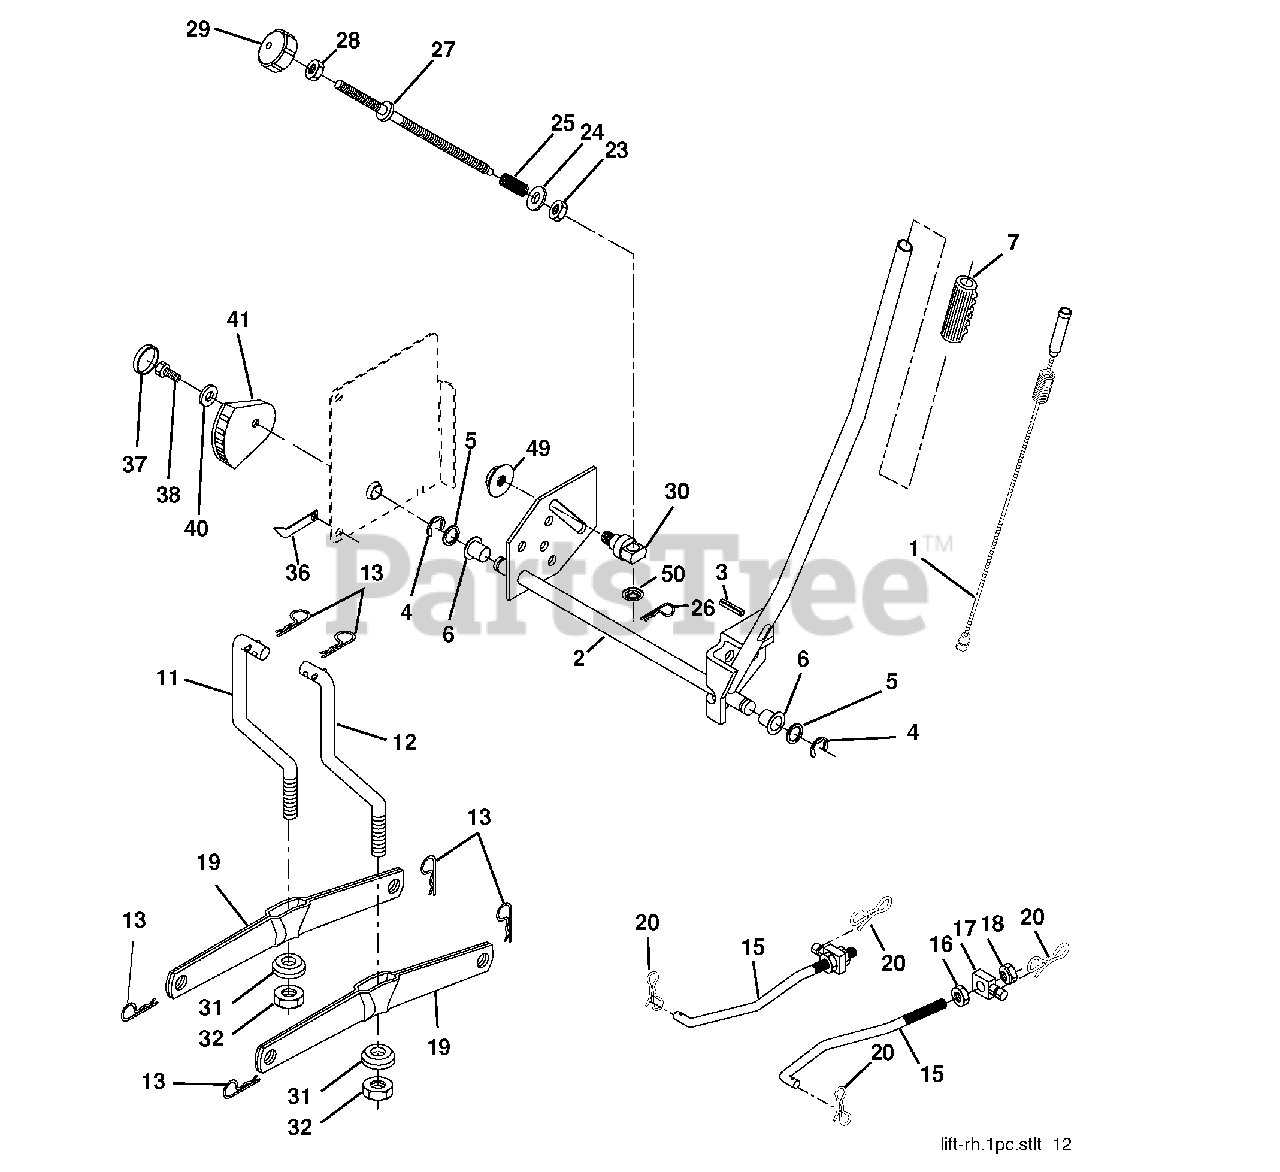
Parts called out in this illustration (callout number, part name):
1	Plunger Asm.
2	Shaft Asm Lift RH w/Inf
3	Pin Groove 2"
4	E Ring #5133-62
5	Washer 21/32 x 1 x 21 Ga.
6	Bearing Nylon Blk 629 Id
7	Grip Handle
11	Link Lift LH Fixed Length
12	Link Lift RH Fixed Length
13	Retainer Spring
15	Link Front
16	Nut Jam Hex 1/2-13 unc
17	Trunnion
18	Nut Lock W/Wsh 1/2-13 unc
19	Arm Suspension Rear
20	Pin Cotter 7/16 Bow Tie Lock
23	Nut Special
24	Washer 13/32 x 5/8 x 16 Ga.
25	Spring Infi n. Height
26	Retainer Clip
27	Rod Adjust Lift
28	Nut Hex Jam 3/8-16 unc
29	Knob Infi n. 3/8-16 unc
30	Trunnion Infi . Height
31	Bearing Pvt Lift
32	Nut Crownlock 3/8 - 24
36	Pointer Height Indicator
37	Plug Hole Blk 1.485/1.515 Dia.
38	Screw 5/16-18 x 1
40	Washer 11/32 x 1-1/2 10 Ga.
41	Indicator Height STLT
49	Nut Hexfl ange Lock
50	Nut Push
